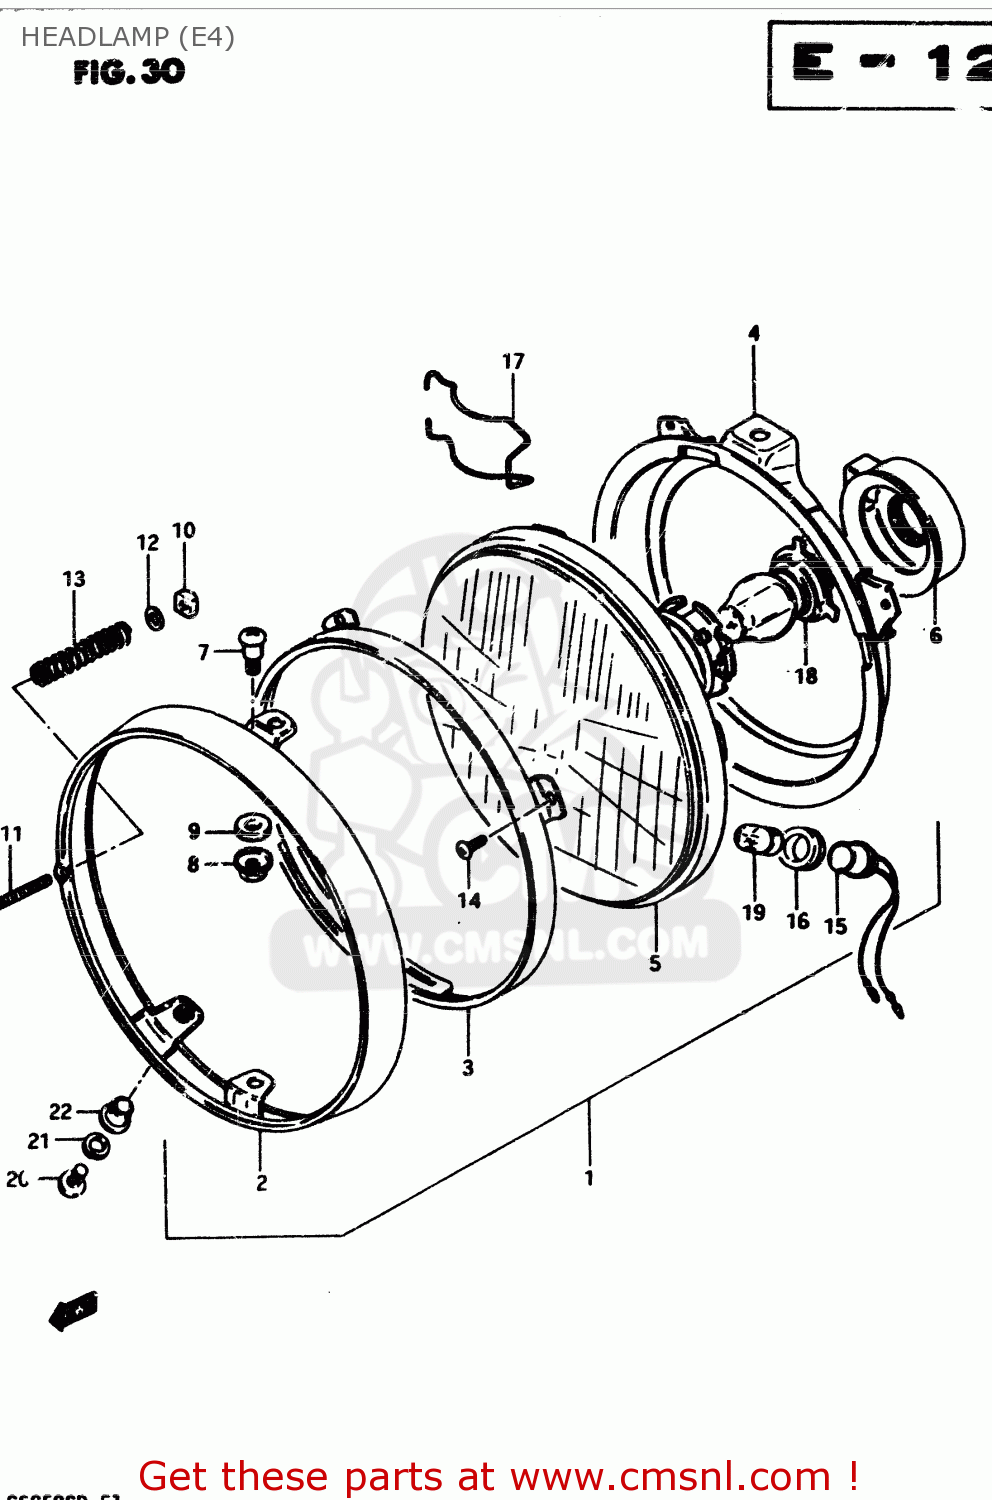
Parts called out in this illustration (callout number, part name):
1	HEADLAMP ASSY
2	RIM
3	RETAINER
4	RING,HEADLAMP UNIT
5	UNIT,HEAD LAMP
6	COVER,HEADLAMP SOCKET
7	SCREW
8	NUT,ADJUSTING
9	SPACER
10	NUT
11	SCREW
12	WASHER
13	SPRING,HEADLAMP ADJUST
14	SCREW
15	SOCKET
16	JOINT,RUBBER
17	CLAMP,HEADLAMP SOCKET
18	BULB (12V, 60/55W, H4)
19	BULB(12V4W)
20	SCREW
21	WASHER,LOCK
22	WASHER
